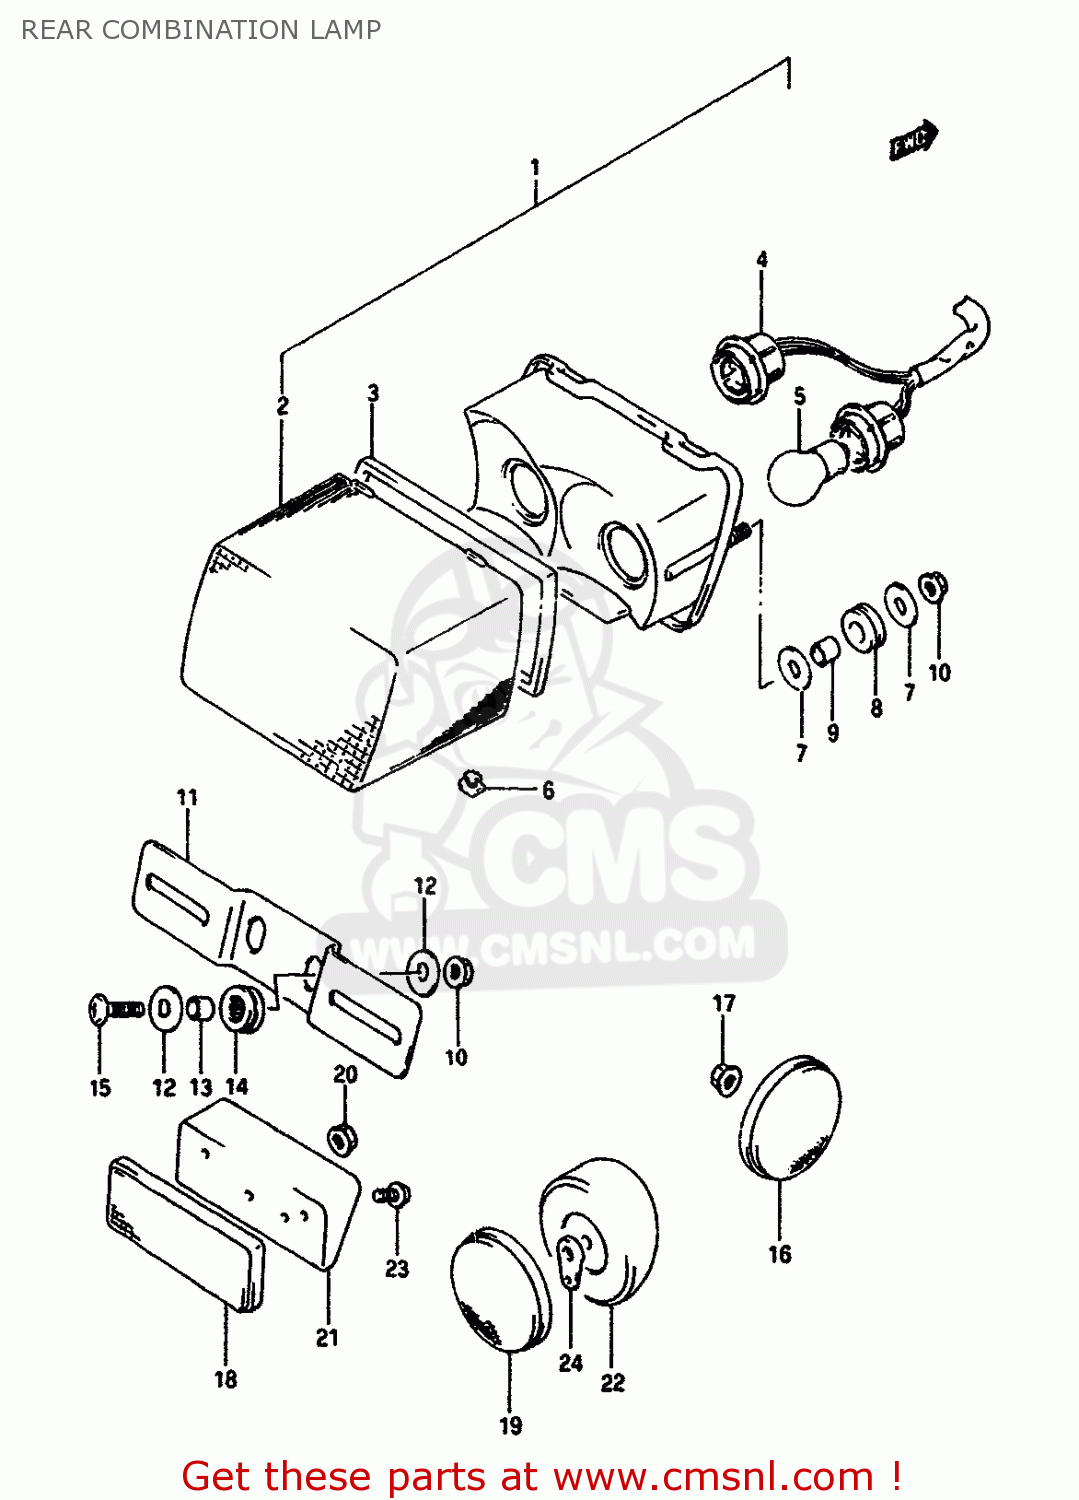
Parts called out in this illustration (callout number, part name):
1	LAMP ASSY,RR COMBINATION
2	LENS
3	GASKET (NAS)
4	SOCKET
5	BULB(12V21/5W)
6	CUSHION
7	WASHER (6.5X20X1)
8	CUSHION
9	SPACER
10	NUT
11	BRACKET,LICENSE PLATE
12	WASHER (6.5X20X1)
13	SPACER
14	CUSHION
15	SCREW(6X25)
16	REFLECTOR,REFLEX FR
17	NUT ,5MM
18	REFLECTOR ASSEMBLY,REAR
19	REFLECTOR ASSY,RR
20	NUT 5MM
21	SPACER,RR RR
22	SPACER, REAR REFLECTOR
23	SCREW
24	WASHER,RR REFLECTOR
